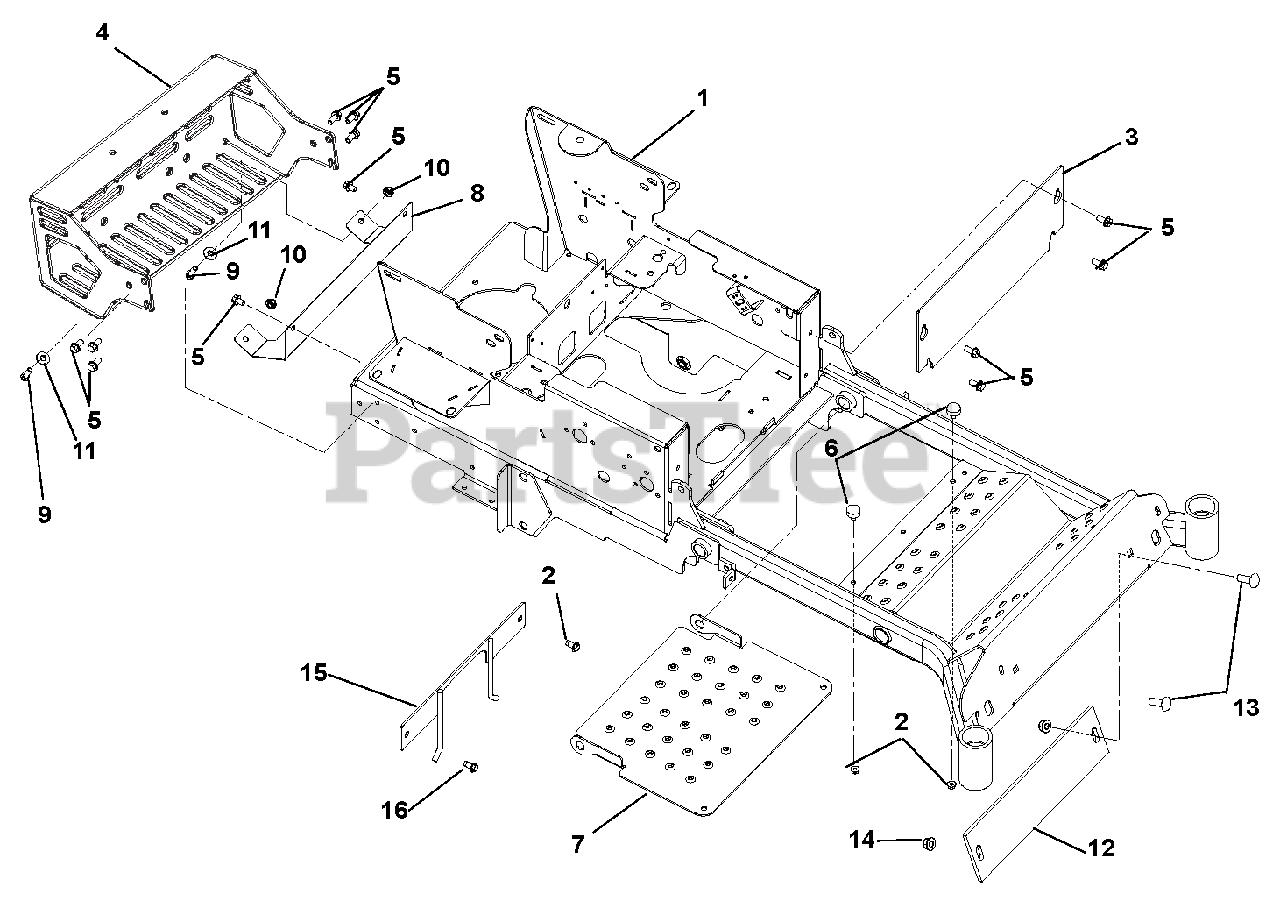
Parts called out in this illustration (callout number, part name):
1	WLDMT, 48" HD FRAME
2	@NUT-SPNLK-FLG .312-18 YWZC
3	PLATE, KICK
4	BUMPER, ARIENS MAX ZOOM
5	@SCR-TAP .38-16X.75 HWH TR YWZ
6	BUMPER, RUBBER
7	PANEL, INSPECTION
8	SHIELD - HEAT - CZ PROD
9	@BLT-HEX .38-16X1.00 GR5 YWZC
10	@NUT-LK-NYL-FLG .38-16 YWZC
11	@WSHR-FL-STL.438X1.00X.083 YWZ
12	COUNTERWEIGHT, CZ FRONT-BLACK
13	BLT-RDHDSQNK .50-13X2.25 G5YZ
14	@NUT-LK-NYL-FLG .50-13 YWZC
15	PTO BELT FINGER WLDMT - BLK
16	@SCR-TAP .38-16X.75 HWH TR YWZ
